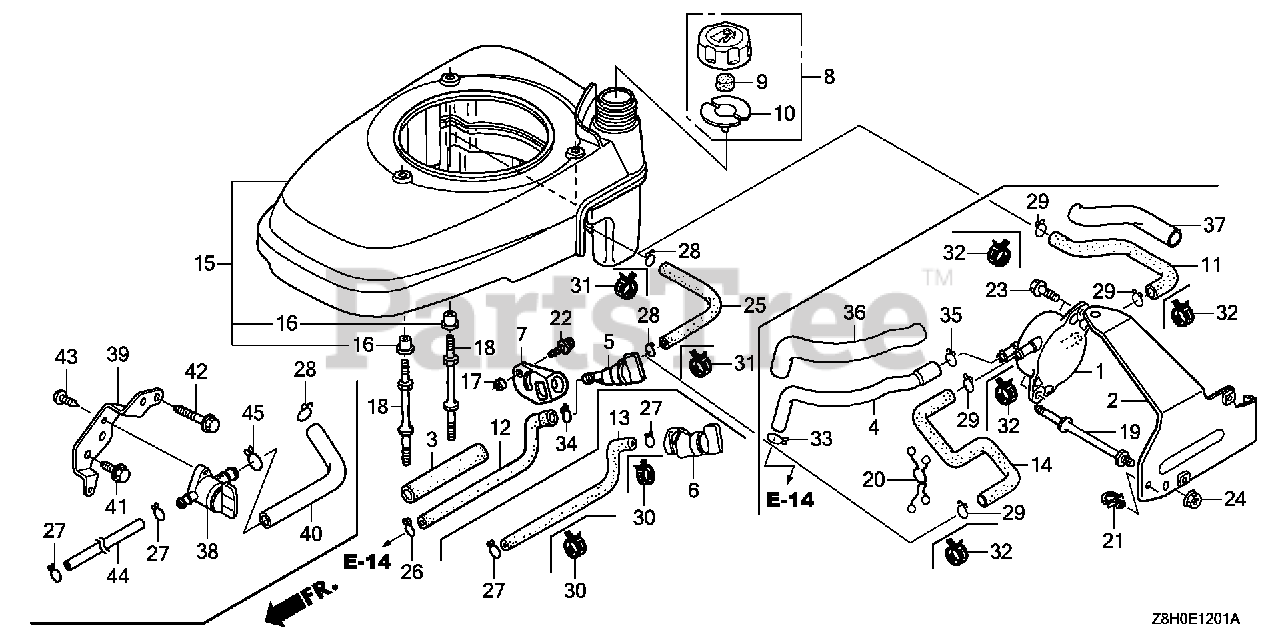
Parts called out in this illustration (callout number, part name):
3	RUBBER, SUPPORTER (107MM)
5	PETCOCK ASSY.
7	BRACKET, PETCOCK
8	CAP ASSY., FUEL TANK
9	SPONGE, FUEL CAP BREATHER
10	GASKET, FUEL CAP
12	TUBE, FUEL
15	COVER, FAN *NH1* (BLACK)
16	COLLAR, FAN COVER
17	COLLAR, FR. TURN SIGNAL
18	BOLT, STUD (H=35.5MM)
22	SCREW-WASHER (5X10)
25	BULK HOSE, FUEL (5.5X3000) (5.3X135)
26	CLIP, TUBE (B8)
28	CLIP, TUBE (B10)
34	CLIP, TUBE (C9)
